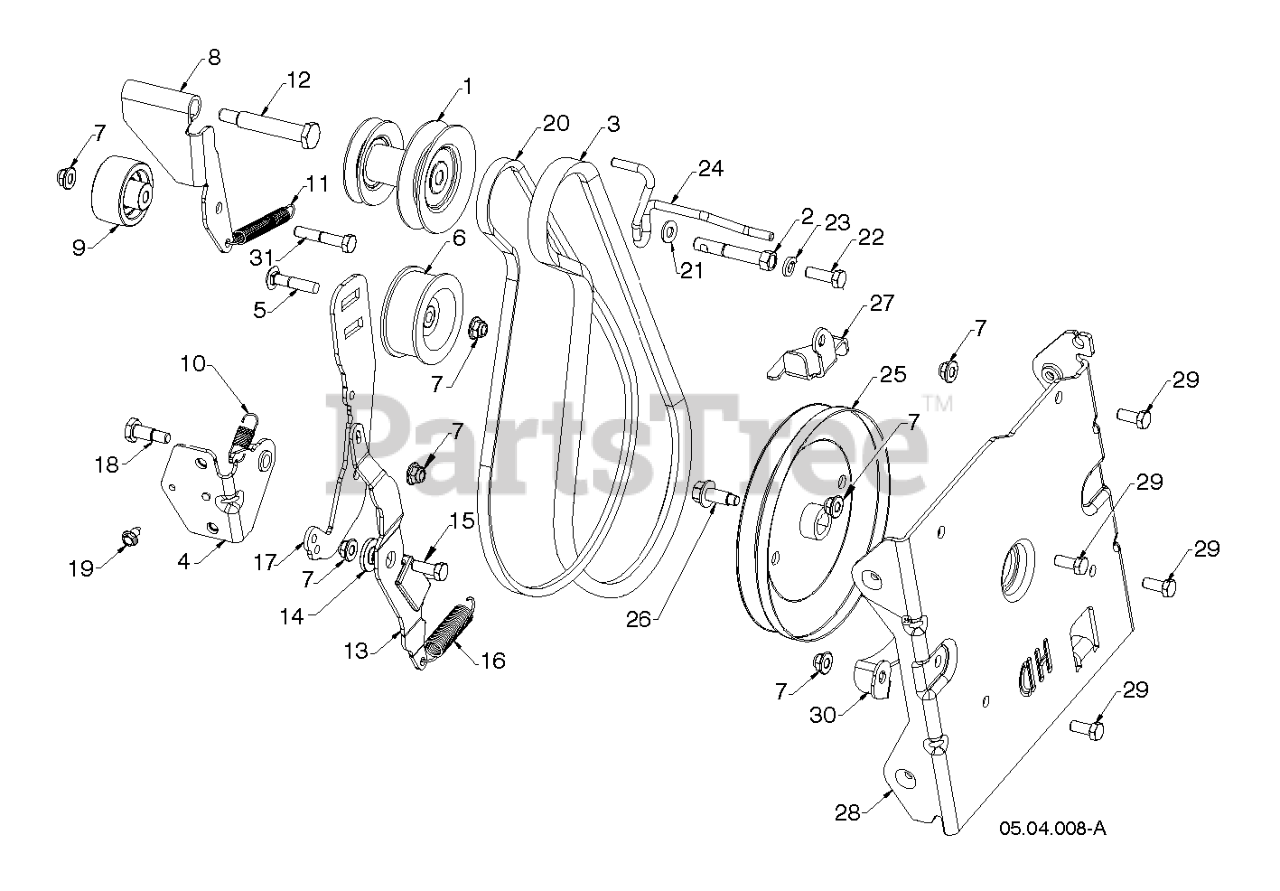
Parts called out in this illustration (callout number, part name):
1	PULLEY WELDMENT
2	BOLT.ENGINE.PULLEY
3	BELT 5L 39.15L
4	BRACKET WELDMENT, IDLER ARM ZI
5	BOLT 5/16-18 CARRIAGE 1.5L
6	PULLEY IDLER
7	NUTNYLOK.FLRANGE.5/16-18
8	ARM DRIVE IDLER CLEAR ZINC PLA
9	PULLEY.IDLER.FLANG.2.O/SPACER
10	SPRING IDLER RETURN
11	SPRING RETURN IDLER ARM
12	BOLT 5/16-24X2.25 HEX HEAD SHO
13	ARM IMPELLER BRAKE
14	BUSHING.BRAKE.ARM
15	BOLT
16	SPRING EXTENSION - BRAKE
17	ARM IDLER BLACK ZINC
18	SCREW HEX HEAD SHOULDER
20	BELT 3L 39.68; POLY CORD
21	WASHER M
22	SCREW 5/16-24 X .75 GR5
23	WASHER.LOCK.HVY.HLCL.SPR.5/16
24	GUIDE BELT - 3L FRICTION, 5L I
25	PULLEY IMPELLER DD 5L HD
26	SCREW FLANGE HEAD CAP WITH DOG
28	BRACKET AUGER HOUSING INTERFAC
29	BOLT.FIN.HEX.5/16-18X3/4
30	BRACKET.BELT.KEEPER.LOWER.BLAC
31	BOLT, HEX 5/16-18X1-3/4
